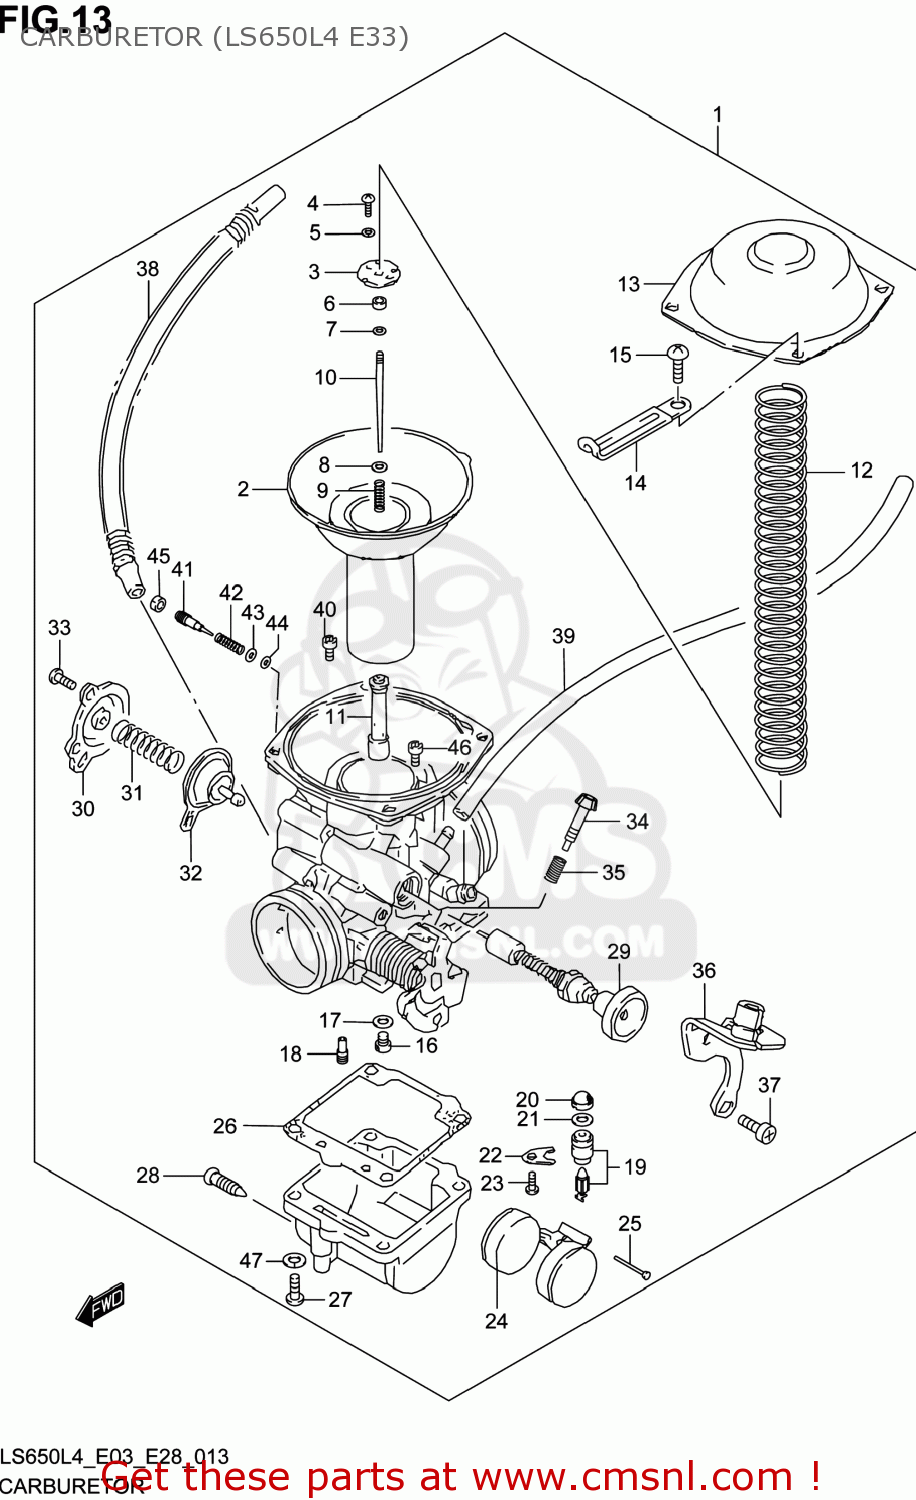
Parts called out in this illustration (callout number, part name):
1	CARBURETOR ASSY
2	DIAPHRAGM ASSY
3	PLATE
4	SCREW
5	WASHER,LOCK
6	RING
7	CLIP,NEEDLE
8	WASHER
9	SPRING
10	NEEDLE,JET(5C17)
11	JET,NEEDLE(X-7M)
12	SPRING
13	COVER
14	CLAMP(L:80)
15	SCREW
16	JET,MAIN(145)
17	WASHER
18	JET,PILOT(52.5)
19	VALVE ASSY,NEEDLE
20	FILTER
21	O RING,NEEDLE VALVE SEAT
22	PLATE,NEEDLE VALVE
23	SCREW
24	FLOAT
25	PIN,FLOAT
26	GASKET,FLOAT CAHMBER (NAS)
27	SCREW
28	SCREW,DRAIN
29	PLUNGER ASSY
30	COVER
31	SPRING
32	DIAPHRAGM ASSY
33	SCREW
34	ADJUSTER
35	SPRING
36	BRACKET ASSY
37	SCREW
38	HOSE ASSY
39	HOSE(5X8.2X600)
40	JET,PILOT(230)
41	SCREW,AIR
42	SPRING
43	WASHER
44	O RING,PILOT AIR SCREW
45	PLUG
46	JET(45)
47	WASHER,LOCK
